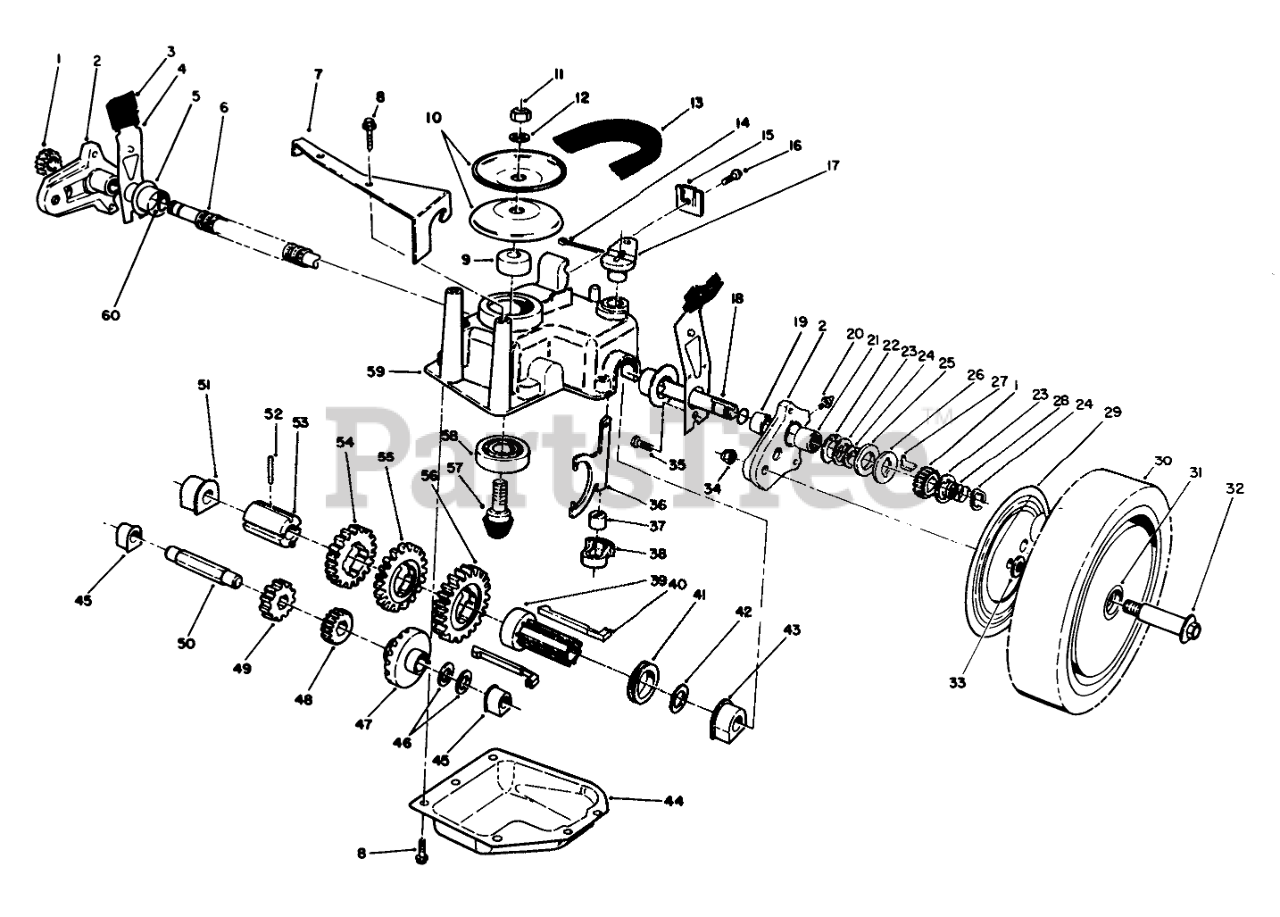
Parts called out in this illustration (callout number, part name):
1	Pinion
2	Pivot Arm Assembly (Incl. Ref. #20, 21)
3	KNOB-ARM
4	SPRING ARM ASM SP
5	CAP-END
6	CONDUIT-CONVOLUTED, SPLIT
7	Bracket-Belt Guide
8	SCREW-HWHTF
9	SPACER
10	Pulley Half
11	NUT-HEX
12	WASHER-FLAT
13	V-BELT E
14	PIN-COTTER
15	Cable Clamp
16	SCREW-HWHTF
17	SHIFT LEVER
18	SHAFT-OUTPUT
19	BUSHING
20	FITTING-GREASE
21	BEARING-ROLLER
22	WASHER-THRUST, KEYED
23	WASHER-ARM, PIVOT
24	RING-CLIP, LOCKING
25	RING-FRICTION
26	WASHER-CLUTCH
27	KEY-ROCKING, RH
28	SPRING-COMPRESSION
29	WHEEL COVER
30	Wheel-Tire & Gear Assembly(Incl. Ref. #31)
31	BUSHING
32	WHEEL BOLT
33	WASHER
34	Nut
35	SCREW-HWH
36	YOKE-SHIFT
37	BUSHING-YOKE
38	RETAINER-FORK, SHIFT
39	Sleeve-Shift Key
40	Key Shift
41	SHIFT COLLAR
42	WASHER-PLAIN
43	BUSHING-OUTPUT
44	Cover-Gearcase
45	BUSHING
46	WASHER-THRUST
47	Gear-Bevel
48	PINION-20T
49	PINION-25T
50	SHAFT-INTERMEDIATE
51	BUSHING
52	PIN-SPRING
53	SLEEVE-GEAR
54	GEAR-39T
55	GEAR-44T
56	GEAR-49T
57	Gear-Pinion
58	BEARING-BALL
59	CASE-GEAR, UPPER
60	O-RING
